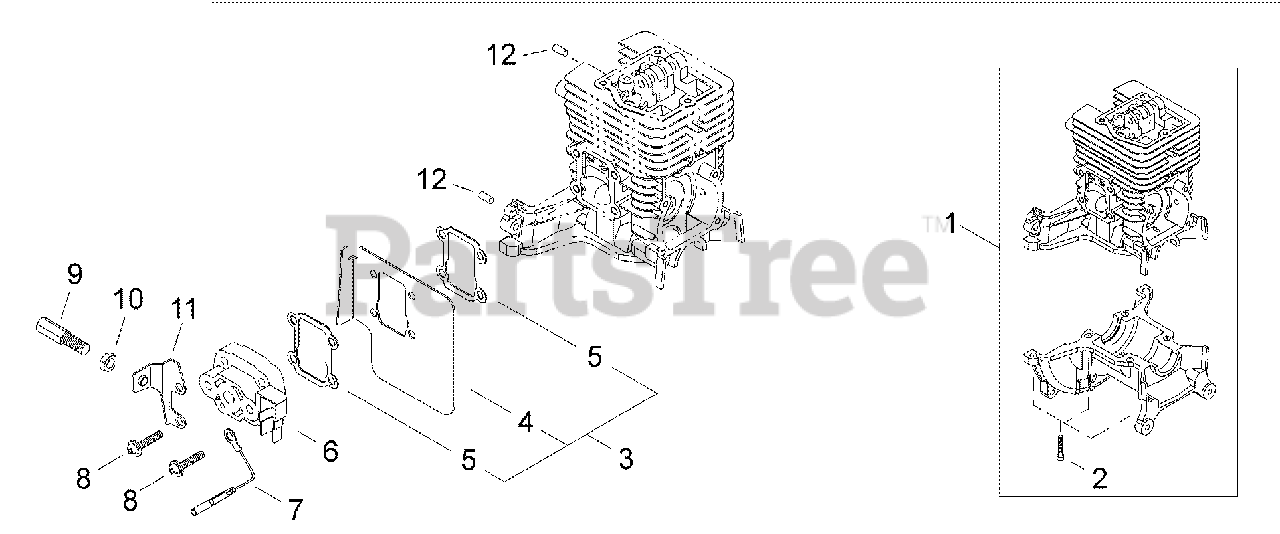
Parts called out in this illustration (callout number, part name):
1	CYLINDER BLOCK SET
2	SCREW - 5X16
3	HEAT DEFLECTOR ASSY
4	DEFLECTOR, HEAT
5	SHIELD, INTAKE
6	INSULATOR
7	LEAD - GROUND
8	SCREW - 5X22
9	NUT, CABLE ADJUST
10	LOCKNUT - 6
11	BRACKET, THROTTLE CABLE
12	PIN - LOCATING
